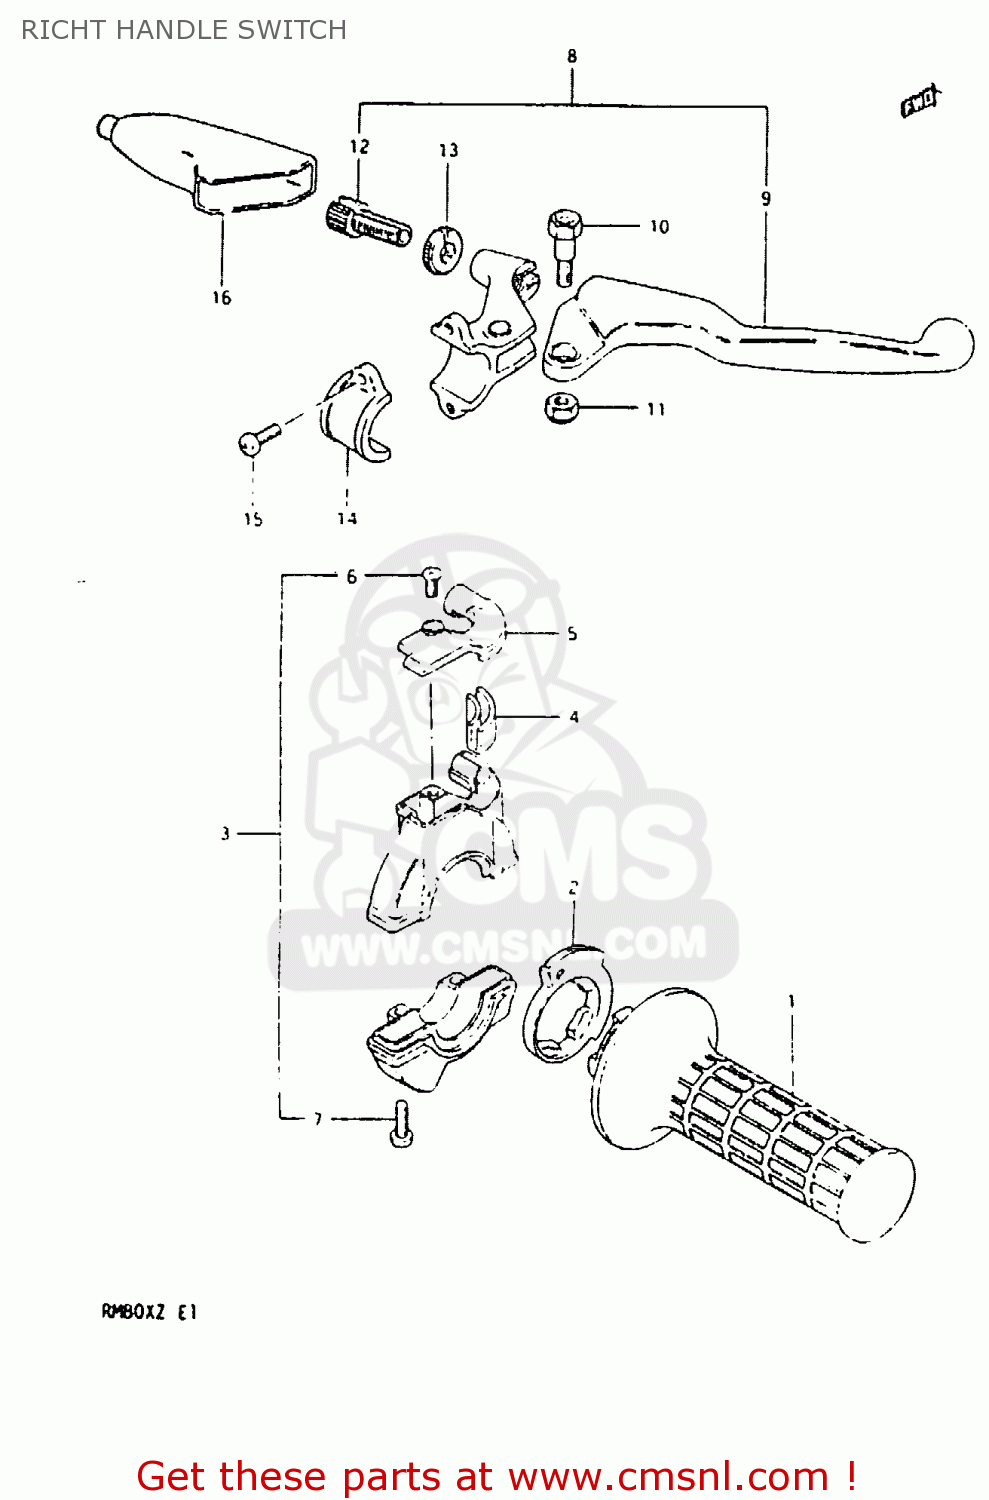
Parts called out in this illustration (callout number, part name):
1	GRIP,THROTTLE
2	ROTOR,THROTTLE GRIP
3	CASE ASSEMBLY,THROTTLE
4	GUIDE PIECE,THROTTLE
5	COVER,THROTTLE CASE
6	SCREW
7	SCREW
8	LEVER ASSY,BRAKE
9	LEVER,BRAKE
10	BOLT,LEVER
11	NUT 6MM
12	ADJUSTER,CABLE
13	NUT,CABLE ADJUSTER
14	BRACKET,CLUTCH LEVER HOLDER
15	SCREW
16	COVER,CLUTCH LEVER
